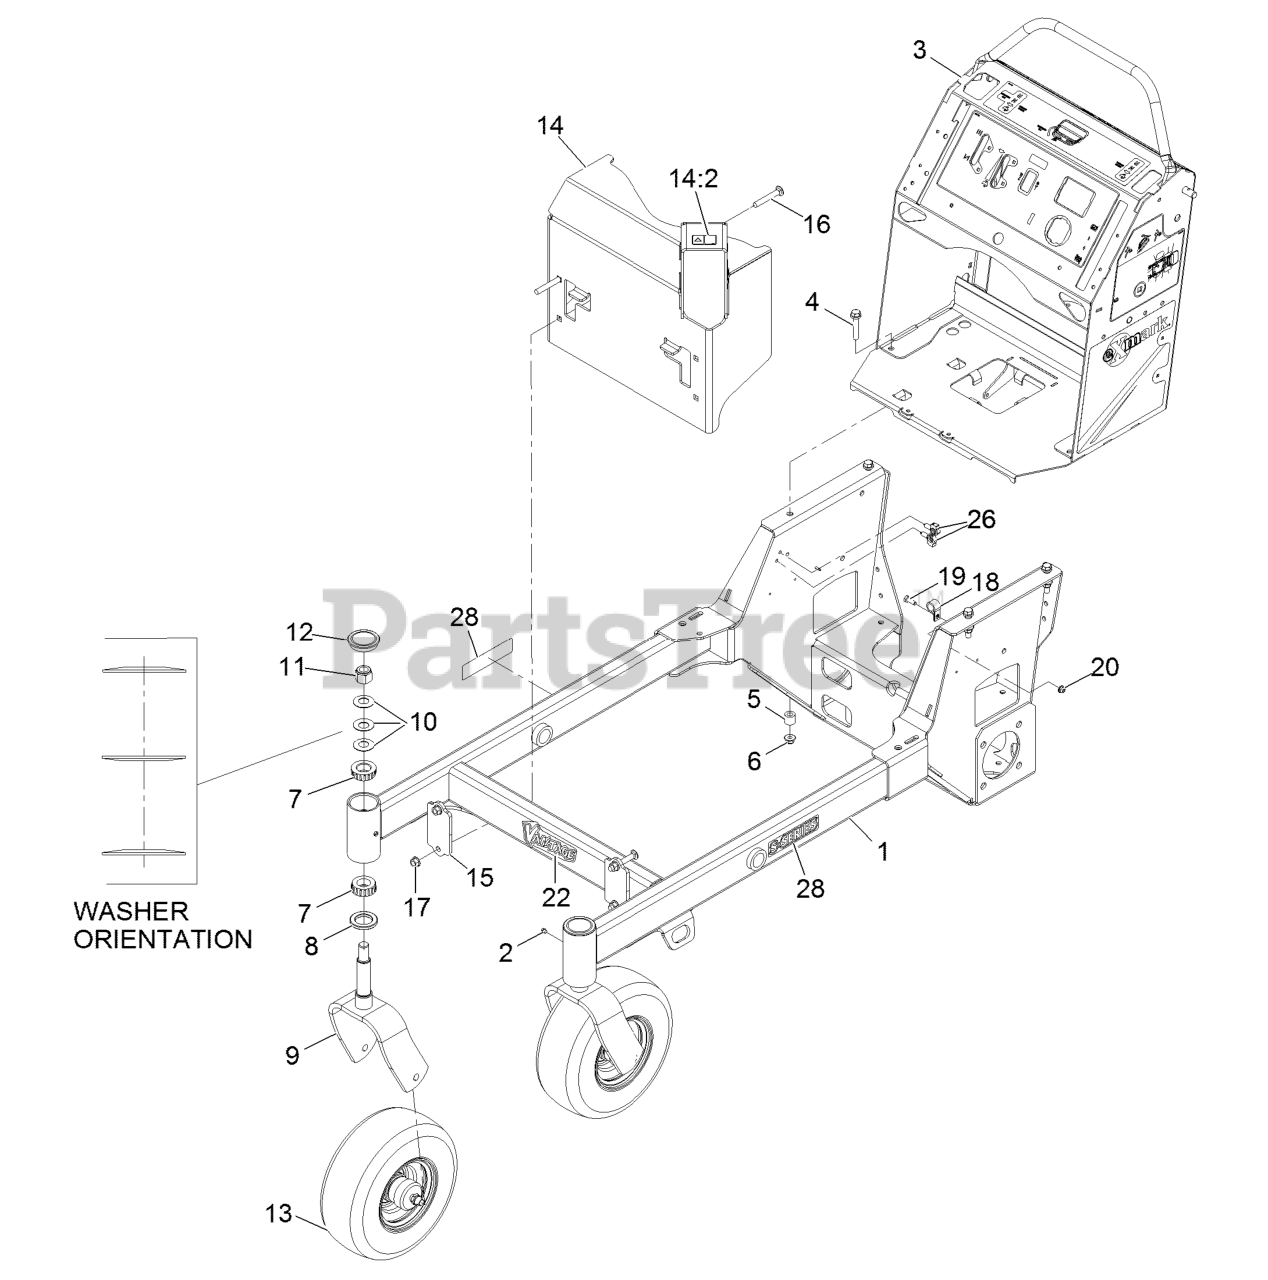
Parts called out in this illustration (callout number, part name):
1	FRAME ASM
3	CONTROL TOWER ASM
4	SCREW-HHF
6	NUT-HF, NI
7	Cone-Bearing Tapered Roller
8	SEAL-GREASE
9	FORK-CASTER
10	WASHER-BELLVILLE
11	NUT-LOCK, NI
12	CAP-GREASE
13	WHEEL/TIRE AND BEARING AS
14	MUFFLER GUARD ASM
14:2	DECAL-WARNING
15	BRACKET-MOUNTING, GUARD
16	SCREW-CARR
18	CLAMP-CABLE
19	SCREW-HH
22	DECAL-VANTAGE LOGO
26	CLIP-HARNESS
28	DECAL-S-SERIES
